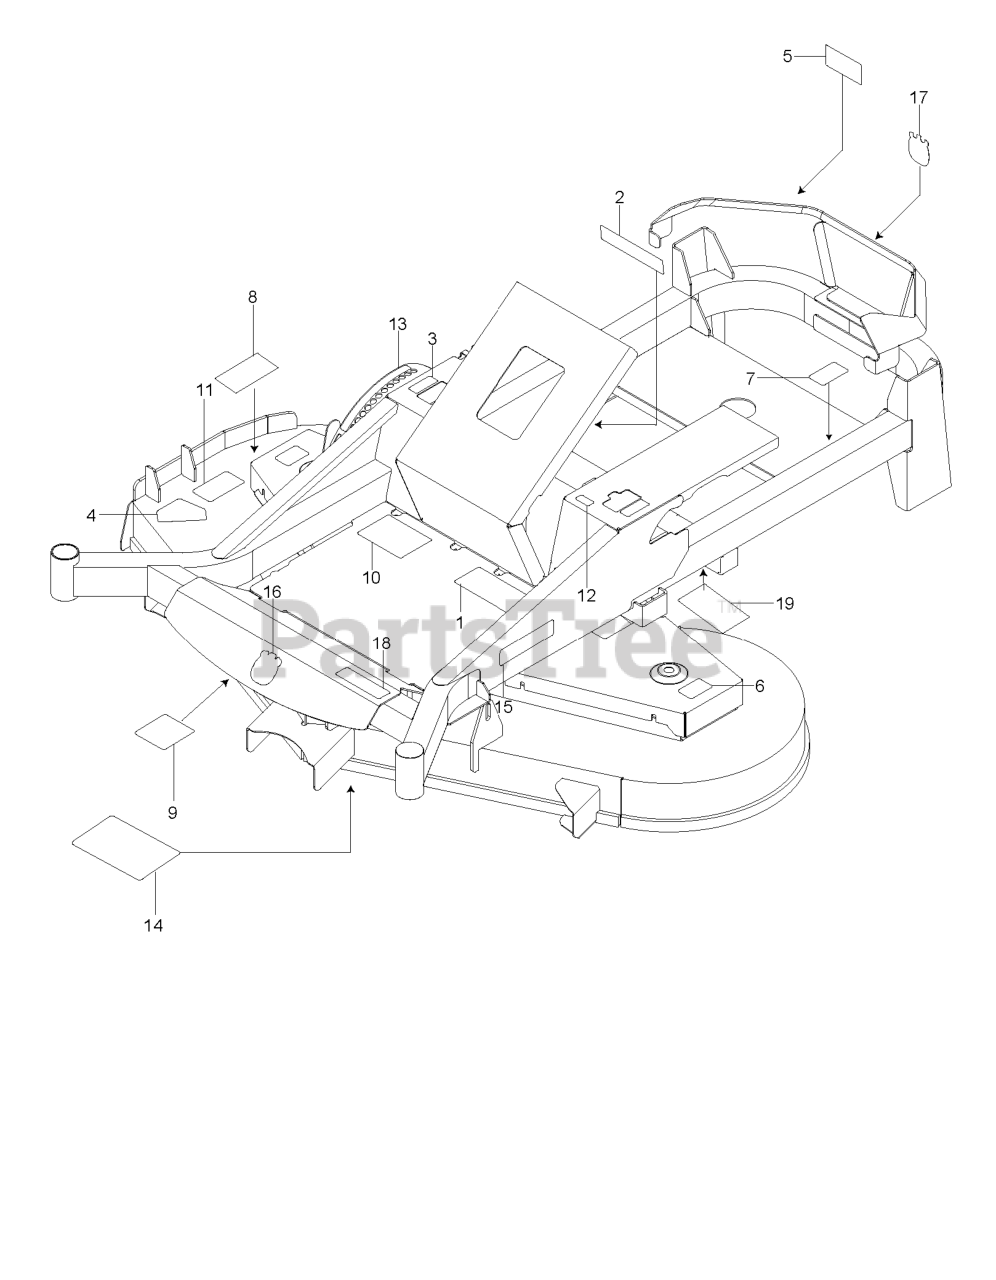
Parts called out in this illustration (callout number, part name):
1	DECAL, WARNING
2	EURO DECAL-BATTERY WARNIN6
3	DECAL, MOTION CONTROL
4	DECAL, CPSC
5	DECAL, BELT DRIVE
6	DECAL, NO STEP
7	DECAL, PROP. 65
8	DECAL, EURO SEVERING
9	RP DECAL, BELT ROUTING
10	DECAL, WARNING
11	DECAL, CAUTION
12	DECAL, F.S.T.
13	DECAL, HEIGHT ADJUST
14	DECAL, SERVICE
15	DECAL.HOOD.LOGO.ORANGE.HUSQVAR
16	DECAL, CROWN H 70MM
17	DECAL, CROWN H, 70MM
18	DECAL, MZ6128
19	HG_DECAL, ZT-3400
